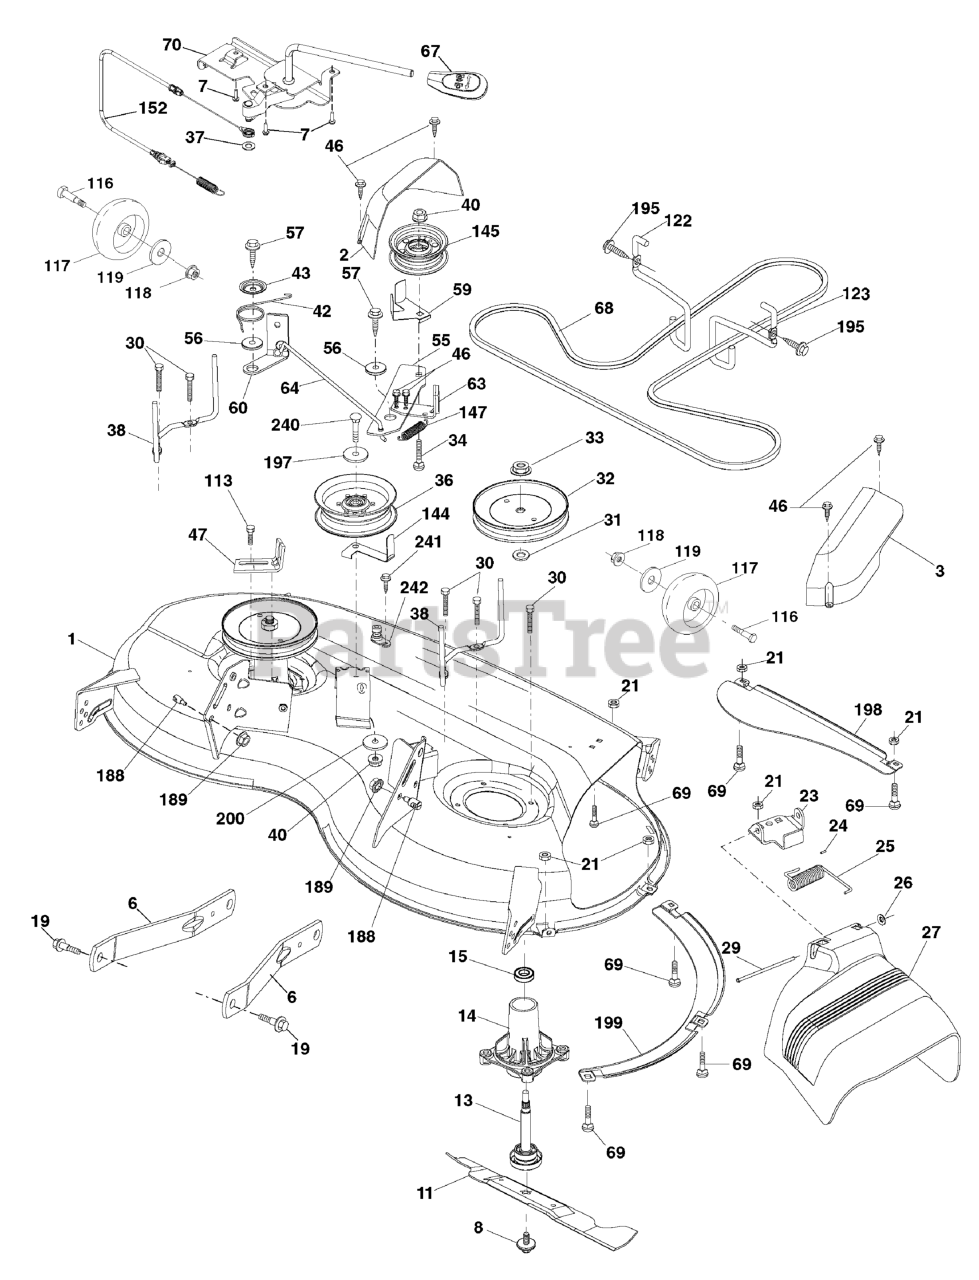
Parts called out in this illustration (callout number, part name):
1	Mower Housing
2	Cover Mandrel LH
3	Cover Mandrel RH
6	Arm Suspension
7	Screw #10 x 0.750 BOS Thread
8	Bolt/Washer asm 7/16-20 unf
11	Blade Mower
13	Shaft Assembly, Mandrel
14	Housing, Mandrel
15	Bearing, Ball, Mandrel
19	Bolt, Shoulder
21	Nut
23	Bracket, Deflector
24	Cap, Sleeve
25	Spring, Torsion, Deflector
26	Nut, Push
27	Shield, Deflector
29	Rod, Hinge
30	Screw Thdrol Rolling Wsh Hd
31	Washer, Spacer
32	Pulley, Mandrel
33	Nut, Toplock, Flanged
34	Bolt Carr Sh. 3/8-16 x 1-1/2 Gr. 5
36	Pulley, Idler, 4.50 RAW
37	Washer 13/32 x 13/16 x 16 Ga.
38	Keeper Belt Mandrel
40	Nut, Lock Flg. 3/8-16 unc
42	Spring Trosion Brake
43	Spring Torsion Retainer
46	Screw
47	Bracket Clutch Cable
55	Arm, Idler
56	Spacer, Retainer
57	Screw Hexwsh Thd 3/8-16 x 1
59	Guard, Tuv Idler (94)
60	Arm Brake Mower LH
63	Arm Brake Mower
64	Linkage Brake
67	Handle, Clutch Cable
68	V-Belt
69	Bolt
70	Clutch Asm.
113	Screw 5/16-18
116	Bolt, Shoulder
117	Wheel, Gauge
118	Nut Centerlock 3/8-16 unc
119	Washer 13/32 x 1-1/4 x 12 Ga.
122	Keeper Belt Eng. LH
123	Keeper Belt Eng. RH
144	Keeper Belt
145	Pulley Idler Primary
147	Spring Return
152	Cable Clutch Manual w/Spr.
188	Stud Fastener
189	Nut Lock Hex Flange
195	Screw 3/8-16 x 3/4
197	Washer 13/32 x 13/16 x 12 Ga.
198	Baffle Center Front
199	Baffle Front RH
200	Washer 13/32 x 1 x 1/2 11 Ga.
240	Bolt 3/8-16 unc x 2-1/4 Gr. 5
241	Screw TT #10-32.5 3/8 Flange
242	Port, Washout
